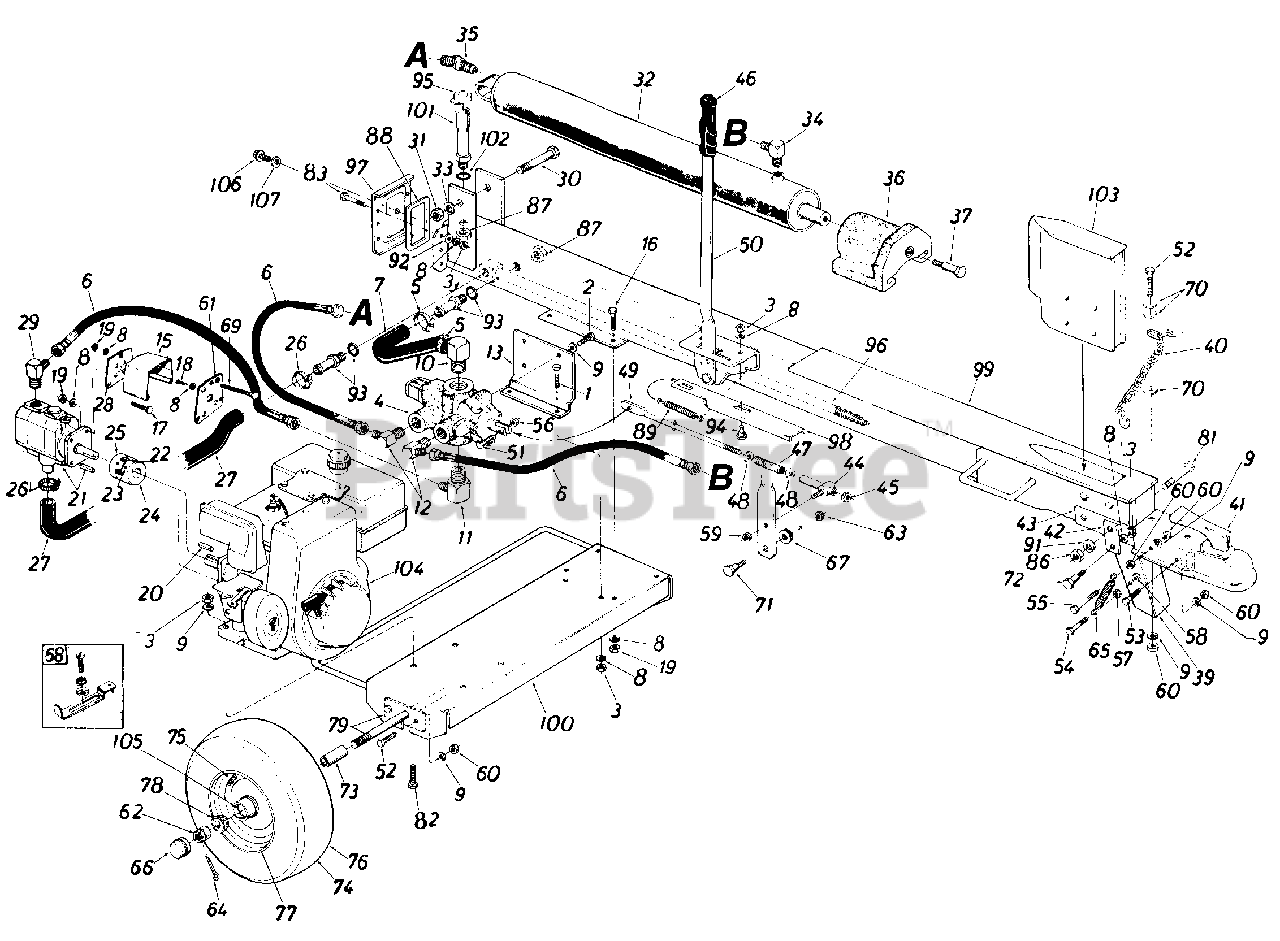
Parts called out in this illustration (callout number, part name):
1	Hex Bolt 5/16-18 x .75" Lg.*
2	Hex Bolt 3/8-16 x .50 Lg.*
3	Hex Nut 5/16-18 Thd.*
4	Control Valve 400
5	Hose Clamp 5/8"
6	High Pressure Hose Ass'y. .38" I.D.
7	Return Hose - Valve to Tank 3/4" I.D.
8	L.-Wash.5/16" I.D.*
9	L.-Wash 3/8" 1 D.*
10	Return Elbow
11	90 Solid Male Adapter
12	90 Solid Male Adapter
13	Valve Mtg. Plate
15	Coupling Shield
16	Hex Bolt 5/16-24 x 1.00" Lg.*
17	Hex Bolt 5/16-24 x .75" Lg.*
18	Hex Bolt 5/16-24 x .62" Lg.
19	Hex Nut 5/16-24 Thd.*
20	Sq. Key 3/16" x 2.25" Lg.
21	Pump with Woodruff Key
22	Spider L-0-90
23	Set Scr. 1/4-20 x .25" Cup
24	Coupling Half .75" I.D.
25	Coupling Half .50" I.D.
26	Hose Clamp 5/8"
27	Suction Hose 1.0" Dia.
29	90ø Solid Male Adapter
30	Hex Bolt 3/4" x 4.0" Lg.
31	Hex Nut 3/4" Thd.
32	Hydraulic Cylinder 3-1/2" Dia.
33	L.-Wash . 314 " I. D.*
34	High Pressure 90ø Elbow
35	45ø Male Adapter 3/4-16 MJ- 3/8-18 NP
36	Pusher Plate
37	Shoulder Bolt .62" Dia. x 4.75" Lg. (1/2-1 Thd.)
39	Flip Stand Bracket
40	Chain-Tow Hitch
41	Tow Hitch Ass'y. Comp.
42	Stand Pivot Bracket
43	Tow Hitch Brk't. 2 x 3/16 10.25" Lg.
44	Ferrule Ass'y.
45	Hex Cent. L.-Nut 3/8-24 Thd.
46	Grip-Black Vinyl
47	Compl'ession Spring
48	Special Washer .378 x 1.00" x .125 Thd.*
49	Engaement Rod 3/8" Dia. x 9.0' Lg.
50	Engagement Handle
51	Hex Bolt 1/4-20 x 1.75" Lg.
52	Hex BoIt 3/8-24 x 1.25" Lg.*
53	Hex BoIt 3/8-24 x .75" Lg.*
54	Hex Bolt 1/4-28 x 1.00" Lg.*
55	Hex Bolt 3/8-24 x 1.75" Lg. (Grade 5)
56	Hex Patch L.-Nut 1/4-20 Lg.*
57	Hex Cent. L.-Nut 1/4-28 Thd.
58	Hex Nut 1/4-28 Thd.
59	Hex Cent. L.-Nut 5/16-18 Thd.
60	Hex Nut 3/8-24 Thd.*
62	Hex Castle Nut 3/4-16 Thd.
63	Hex L.-Nlit 3/8-16 Thd.
64	Cotter Pin 5/32" Dia. x 1.25" Lg.
65	Extension Spring .50" O.D. 3.97 " Lg.
66	Hub Cap
67	Rubber Washer
68	Throttle Control
69	Hex Bolt 5/16-24 x 4.0" Lg.*
70	Fl.-Wash. .375" I.D. x .870" O.D. x .090
71	Shoulder Bolt .498" Dia. x .340" Lg.
72	Shoulder Bolt .437" Dia. x .268" Lg.
73	Spacer .75" I.D. x 1.12" O.D. x 1.56" Lg.
75	Air Valve- Tubeless
76	Tire Only 16.0 x 4.0-2 Ply
78	Roller Rearing 3/4" I.D.
79	Axle Ass'y. .75" Dia. x 36.25" Lg.
81	Hex Bolt 5/8-18 x 3.50" Lg.*
82	Hex Bolt 5/16-24 x 1.75 Lg.*
83	Hex Bolt 5/16-18 x 1.50" Lg.*
86	Hex Nut 5/1-18 Thd.*
87	Hex Nut 11/16-12 Thd.
88	Gasket 2.62 x 5.12
89	Extension Spring .50" O.D. x 4.25" Lg.
91	L.-Wash. 5/8" I.D.*
92	Fl.-Wash. 34" I.D. x .68" O.D. x .062 Thk.
93	IAdapter 1.0" Tube 11/16-12 "O"-Ring
94	Shoulder Bolt .437" Dia. x .180" Lg.
95	Breather Cap
96	Strainer Tube Ass'y.
97	End Plate
98	Engagement Brk't. 1.39 x 11.75" Lg.
99	Complete Oil Tank Ass'y.
100	Engine Frame Ass'y.
101	Filler Tube Ass'y.
102	"O"-Ring92" I.D. x 1.16" O.D. x .116 Dia.
103	Wedge Ass'y.
104	5 H.P. Enginel
105	Bearing Seal
106	Hex Hd. Tap Scr. 5/16"
107	Gasket
